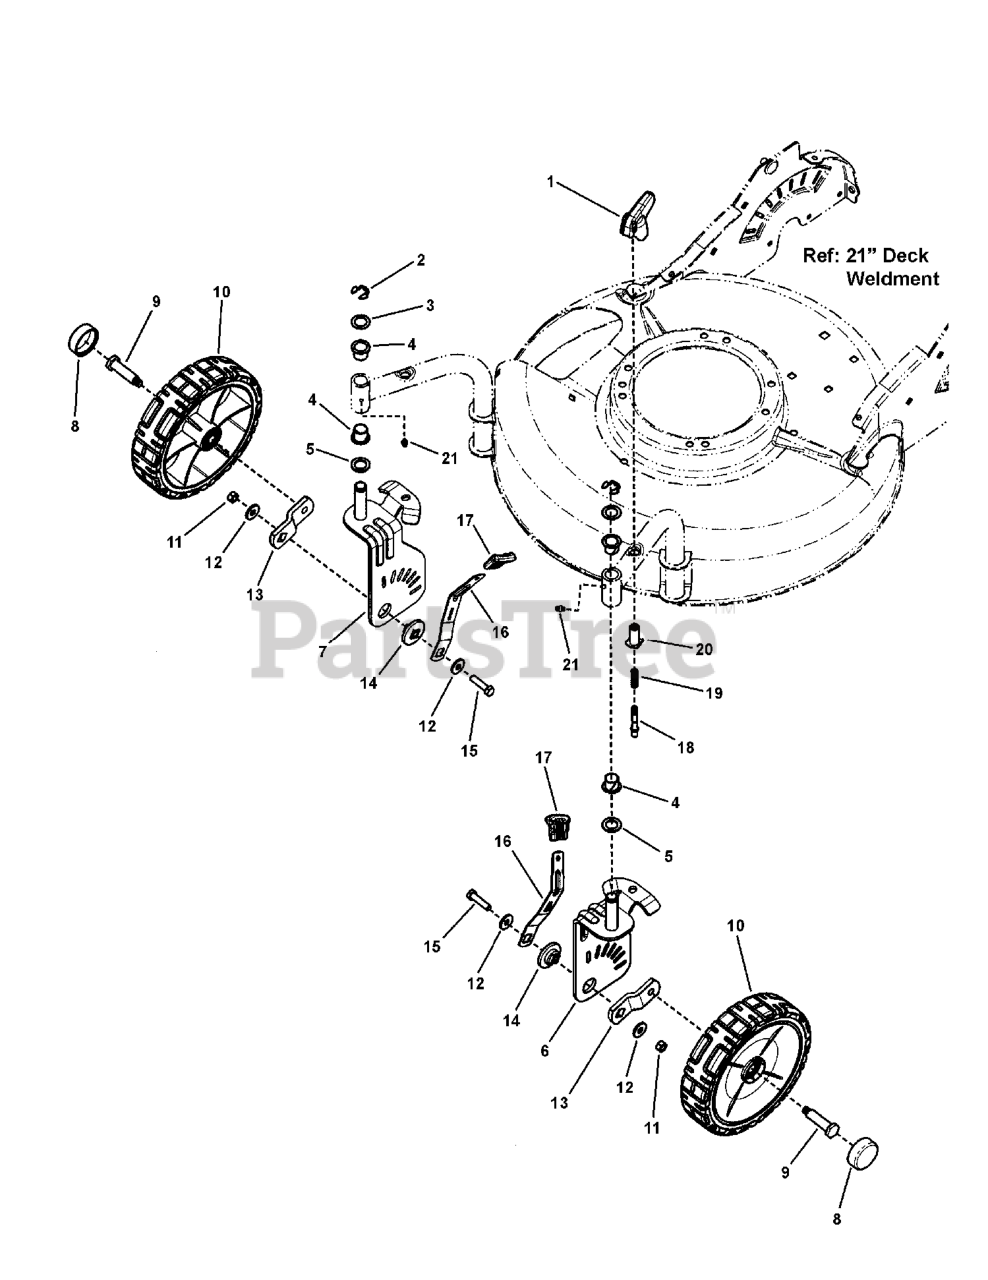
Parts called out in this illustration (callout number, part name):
1	KNOB, Quick Release
2	RING, Klipring Ext for .625 Dia. Shaft
3	WASHER, .64 x .99 x .025 Flat, YZ
4	NYLINER, 5/8
5	WASHER, .64 x .99 x .05 Flat, YZ
6	WELDMENT, Swivel Wheel Bracket, LH
7	WELDMENT, Swivel Wheel Bracket, RH
8	HUBCAP, Round, Black
9	AXLE, Swivel Wheel, 1-5/8
10	ASSY, Wheel, 8 x 2 Idle, Snapper Tread Snapper Charcoal Gray
11	NUT, 5/16-18 Hex Center Lock, YZ
12	WASHER, .875 x .327 x .090, Flat, YZ
13	AXLE PLATE, Swivel Wheel
14	SPACER, Swivel Wheel Pivot
15	SCREW, 5/16-18 x 1-1/4", Hex Head Cap, GR 5, YZ
16	LEVER, Height Adjust, Swivel Wheel
17	GRIP, Height Latch, Black
18	PIN, Handle Adjust
19	SPRING, Compression
20	BUSHING, Handle Pin
21	LUBE FITTING, 3/16" Press Fit
